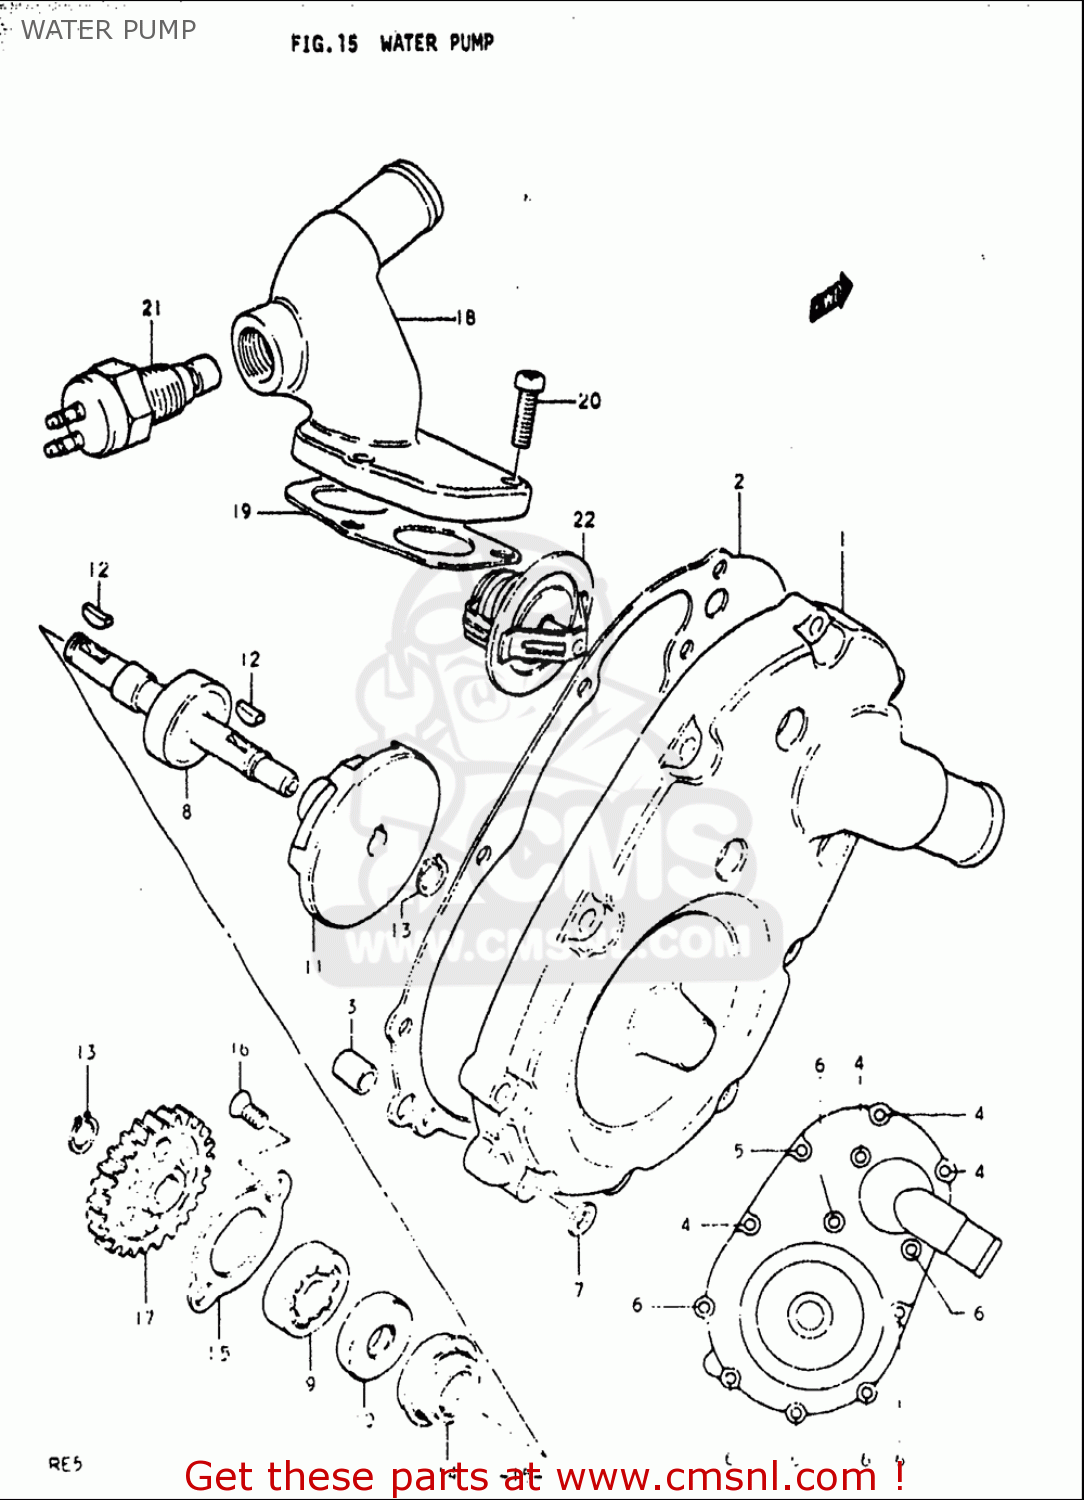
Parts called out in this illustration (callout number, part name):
3	PIN
6	BOLT
7	WASHER
9	BEARING
12	KEY
13	CIRCLIP
16	SCREW
20	SCREW
